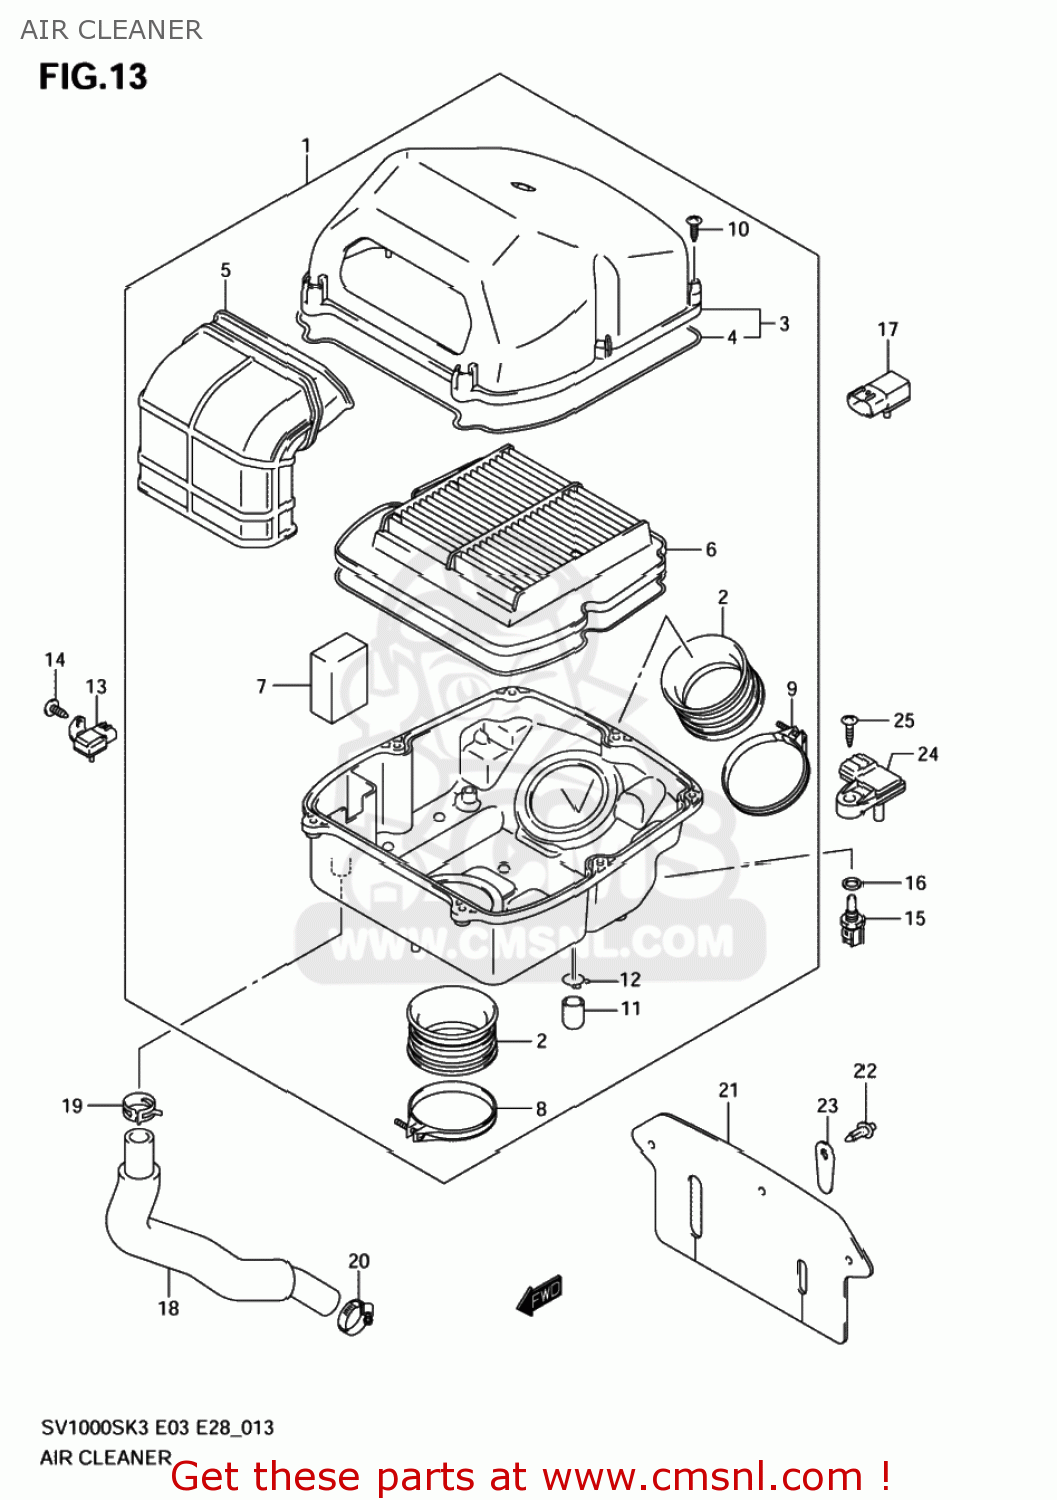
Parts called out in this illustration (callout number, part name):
1	CLEANER ASSY,AIR
2	TUBE,OUTLET
3	CAP,AIR CLEANER
4	GASKET (NAS)
5	TUBE,INLET
6	FILTER
7	FILTER,BREATHER
8	CLAMP
9	CLAMP
10	SCREW
11	PLUG
12	CLIP
13	SENSOR,BOOST
14	SCREW
15	SENSOR,WATER TEMP
16	GASKET(12X17X1) (NAS)
17	SENSOR,AIR PRESSURE
18	TUBE,BREATHER
19	CLIP
20	CLAMP
21	GUARD,WATER
22	CLIP
23	PLATE,WATER GUARD
24	SENSOR,BOOST
25	SCREW
